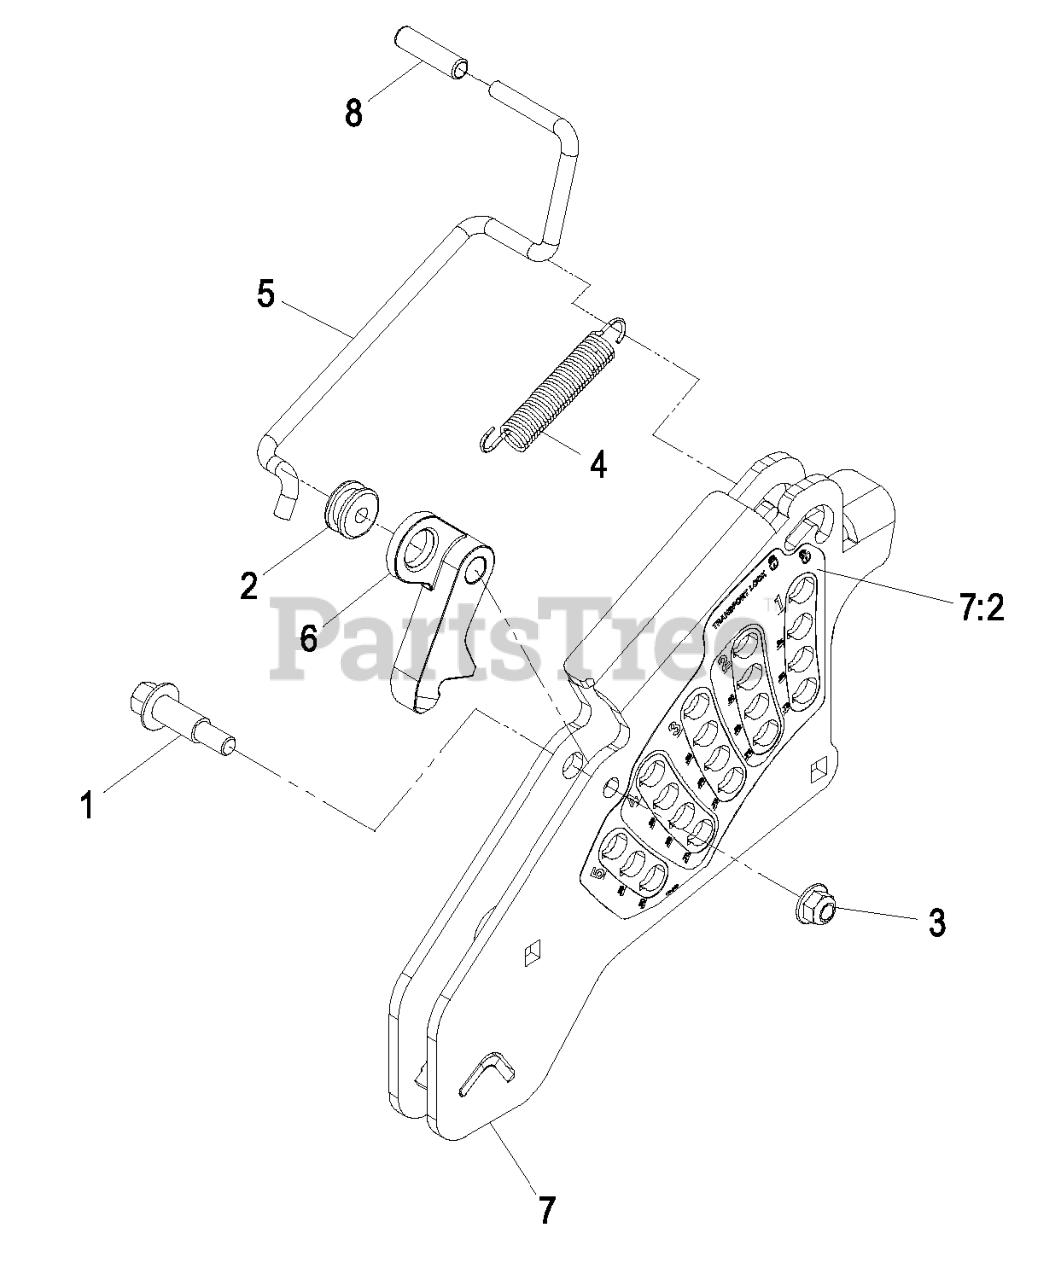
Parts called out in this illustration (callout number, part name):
1	BOLT-SHOULDER
2	GROMMET
3	NUT-HF, NI
4	SPRING-EXTENSION
5	ROD-LOCK, TRANSPORT
6	PAWL-TRANSPORT, HOC
7	HOC PLATE ASM
7:2	DECAL-HOC
8	GRIP-LEVER
